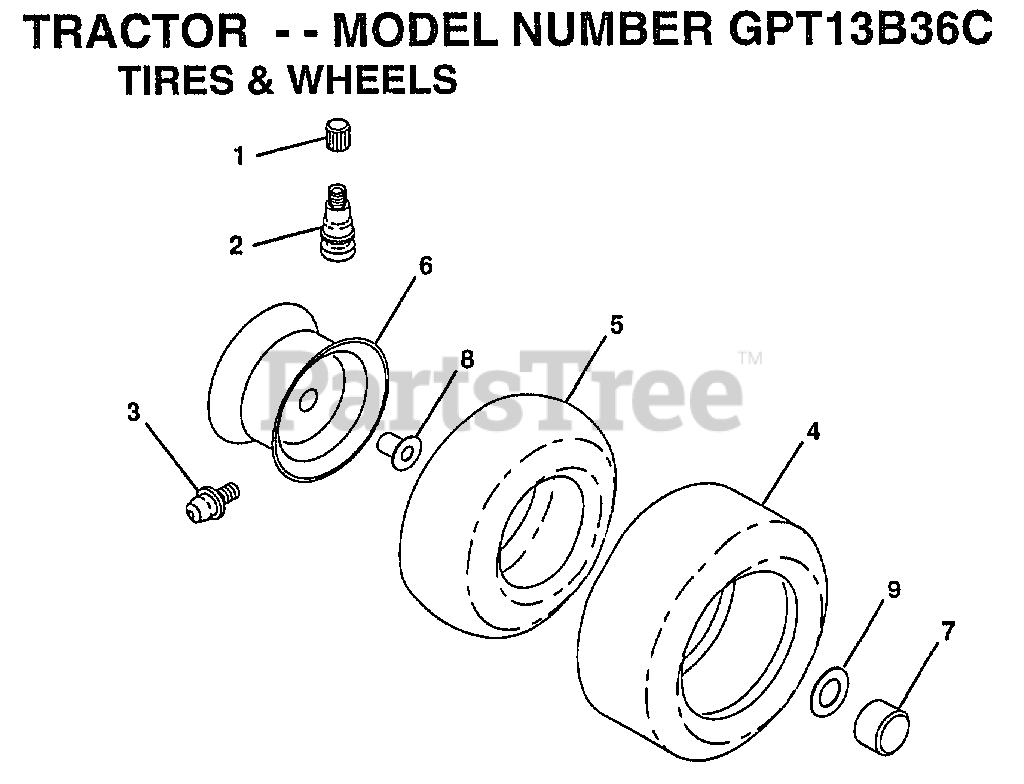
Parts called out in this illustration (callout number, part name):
1	VALVE CAP
2	VALVE STEM LT
3	FITTING LT
4	TIRE
5	TUBE.5.3/4.5/6
5	TUBE.16X6.5/7.5-8
6	"RIM FRONT 6"""
6	"RIM ASM REAR 8"""
7	HUB CAP
8	"FLANGE, BEARING"
9	WASHER
